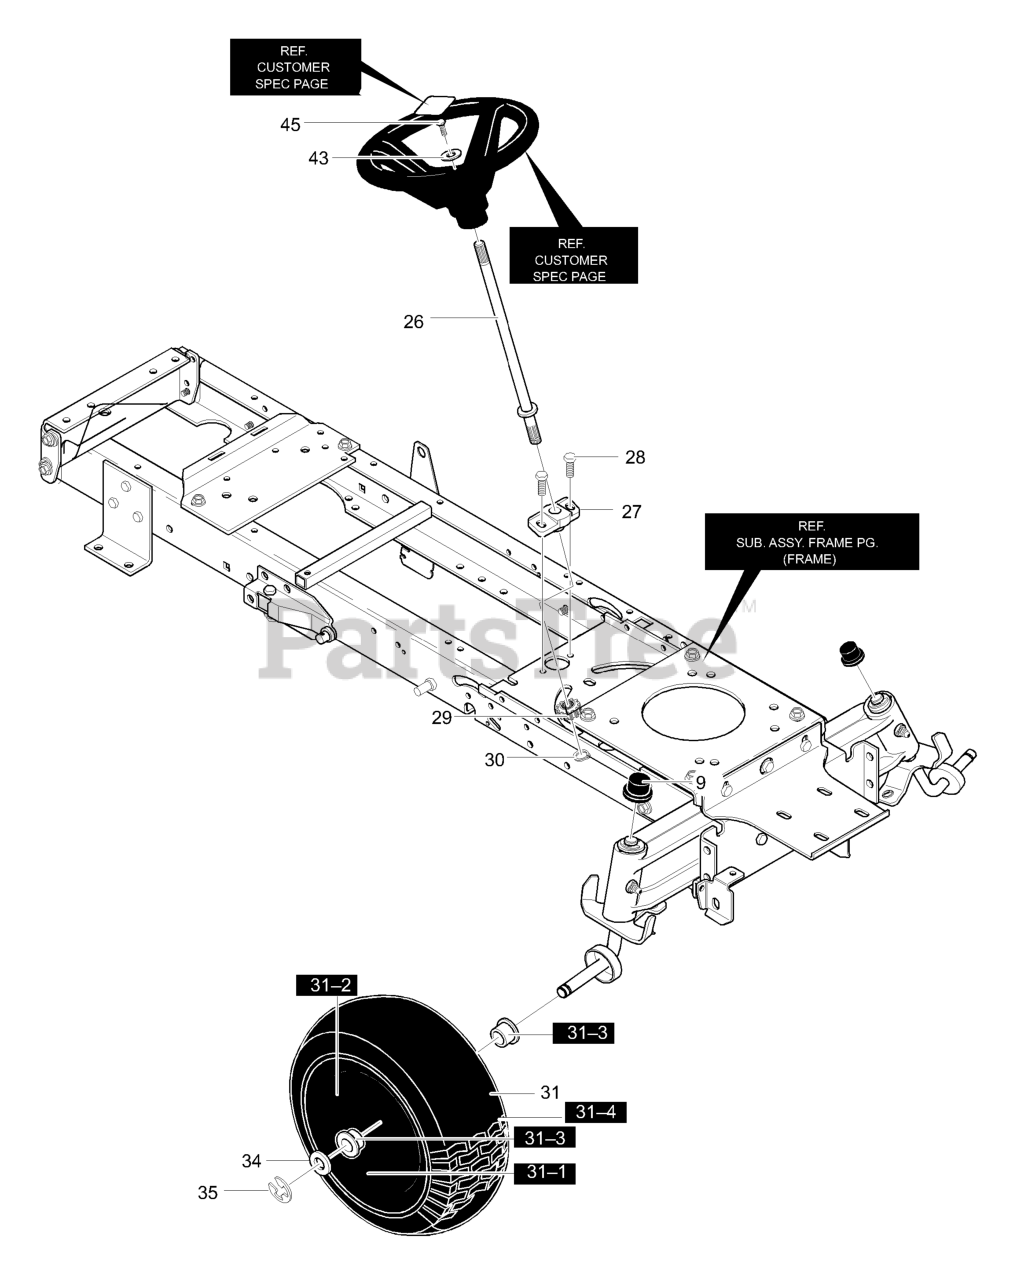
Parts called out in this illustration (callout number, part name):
9	Dust Hub Cap
26	Shaft, Steering
27	Bearing-Lower
28	Screw, 5/16-18 x 0.75
29	Gear, Pinion
30	Retaining Ring
31	Tire & Rim
31-1	Valve Stem
31-3	Bearing
34	Flatwasher
43	Flat washer
45	Screw 1/4-20X.75
